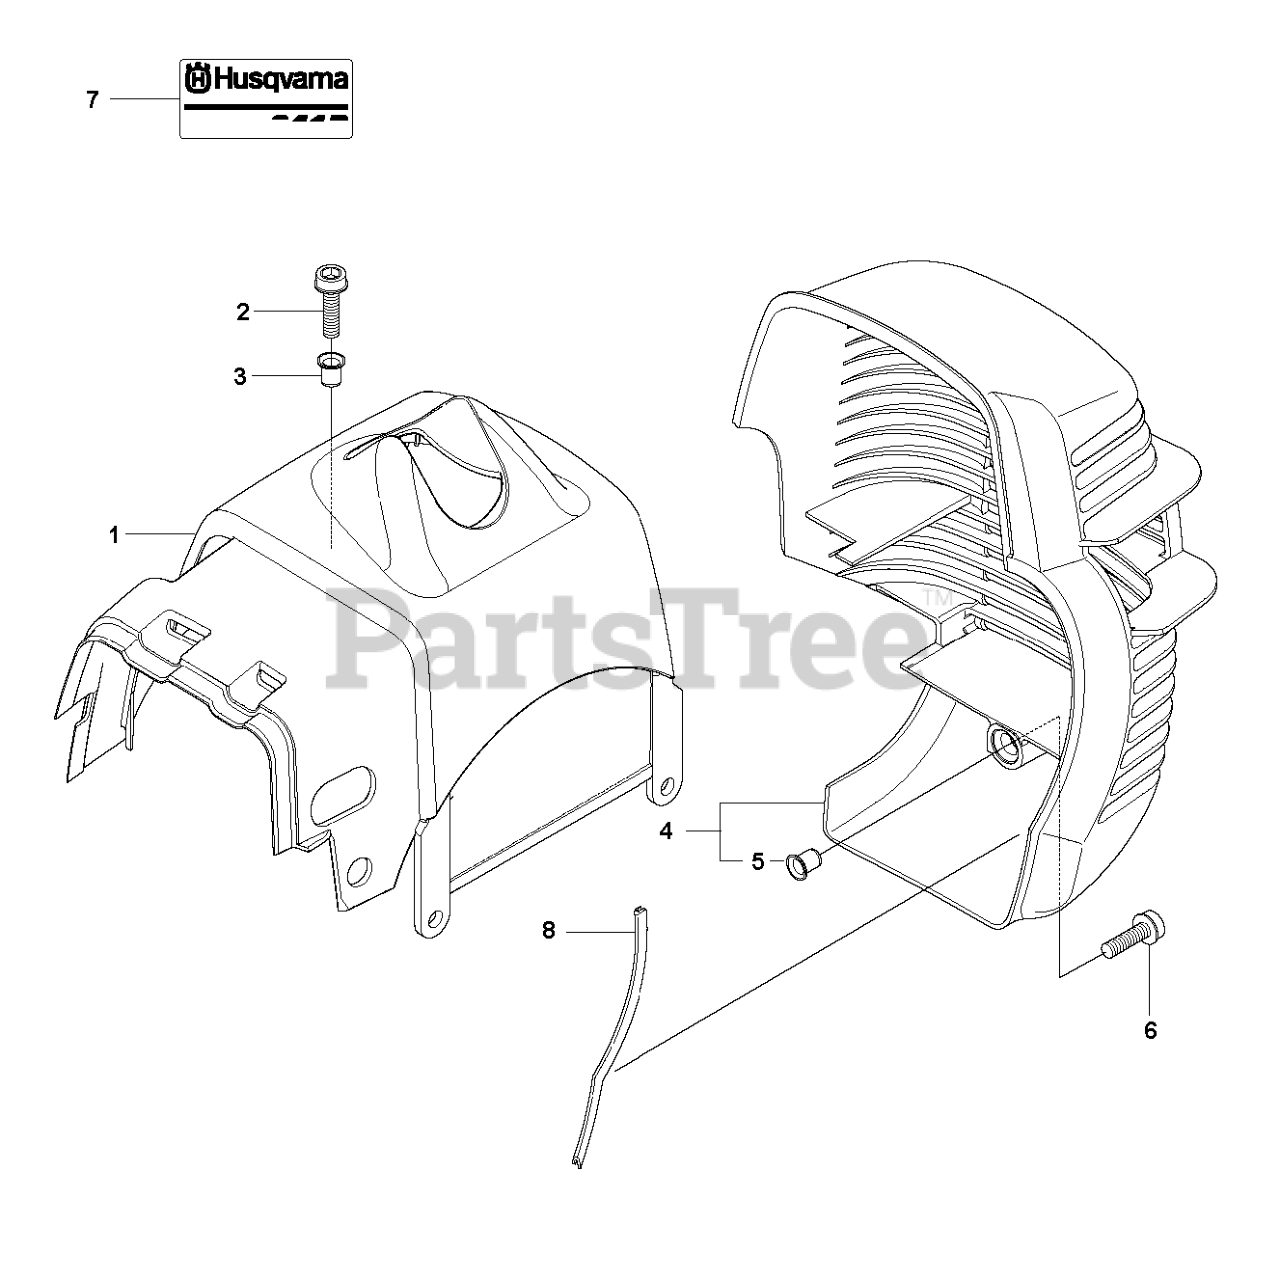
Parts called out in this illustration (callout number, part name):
2	SCREW IHSCFM
4	PROTECTOR
6	SCREW IHSCFM
